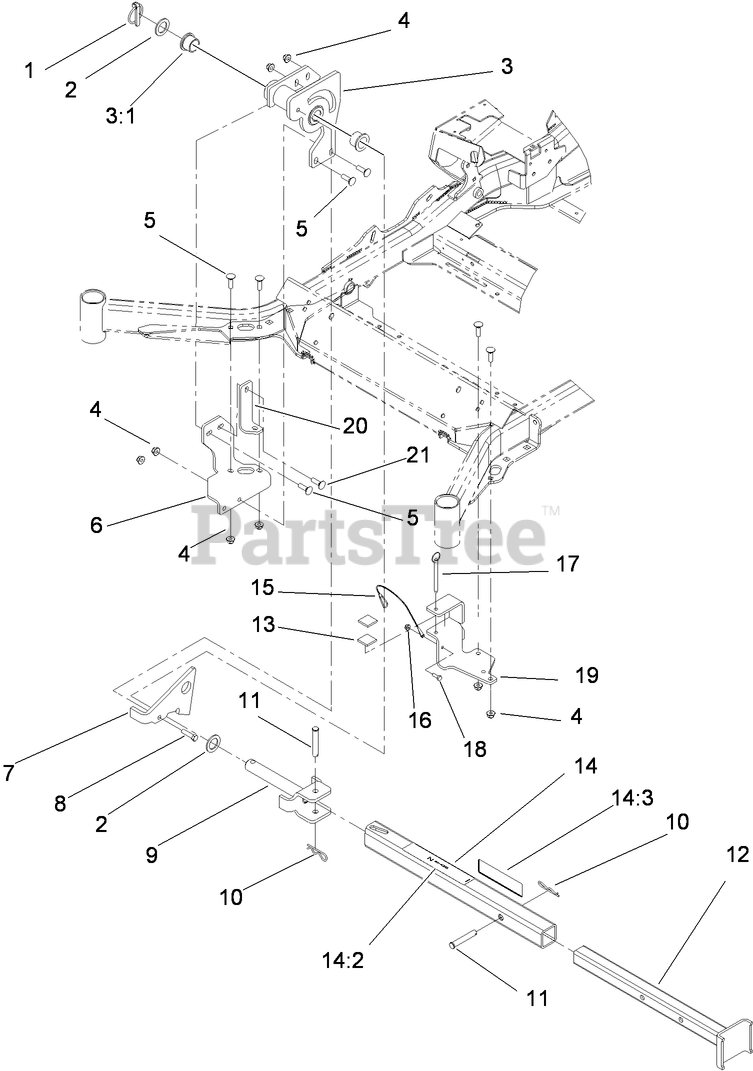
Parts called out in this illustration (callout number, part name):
1	PIN-LYNCH
2	WASHER-THRUST
3	Z STAND PIVOT ASM
3:1	BUSHING
4	NUT-HF, NI
5	BOLT-CARR
6	BRACKET-Z STAND, PIVOT MOUNT
7	BRACKET-LATCH
8	SCREW-HH
9	PIN-PIVOT
10	PIN-HAIR
11	PIN-CLEVIS
12	TUBE-INNER
13	CUSHION-RUBBER
14	OUTER TUBE ASM
14:2	DECAL-Z STAND
14:3	DECAL-WARNING
15	LANYARD-NYLON
16	NUT-HF
17	PIN-HITCH, COTTERLESS
18	SCREW-HH
19	CRADLE-Z STAND
20	BRACKET-SUPPORT
21	SCREW-CARR
